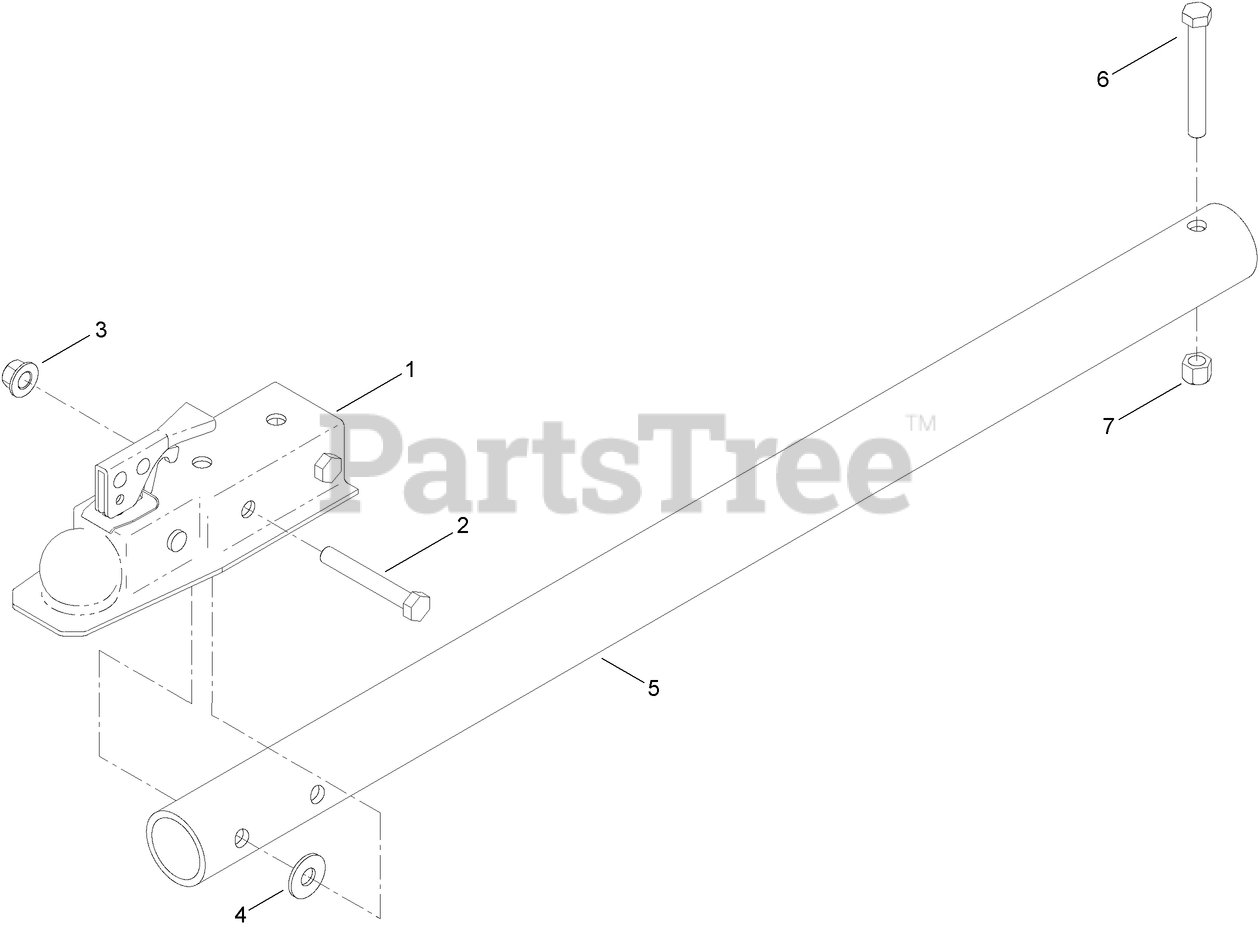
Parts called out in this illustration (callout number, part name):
1	COUPLER-BALL 2IN ZINC
2	SCREW-HH
3	NUT-LOCK
4	WASHER-FLAT
5	PIPE-TOW POLE
6	SCREW-HH
7	NUT-LOCK, NI
